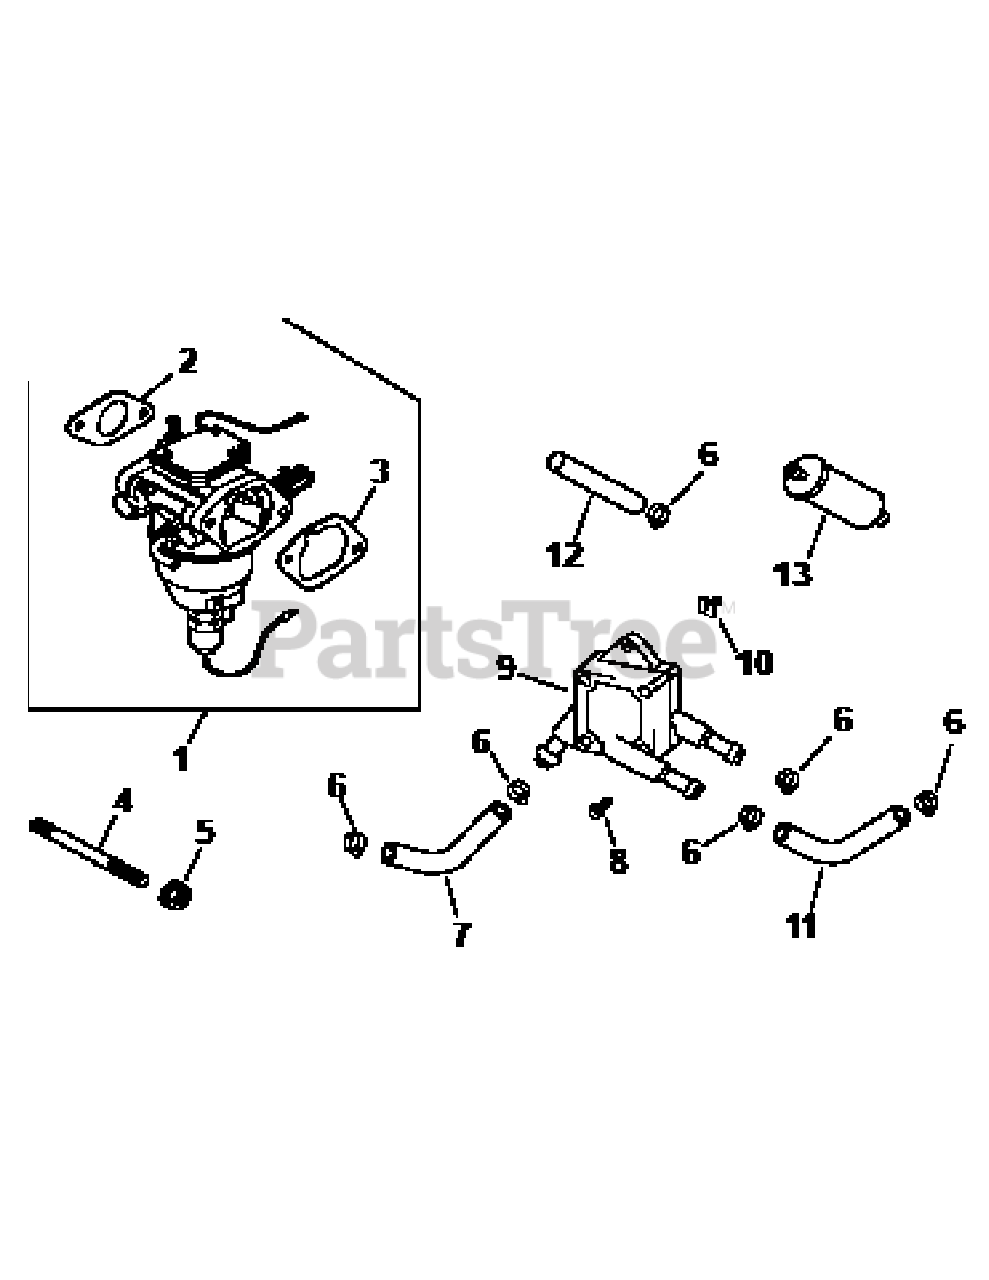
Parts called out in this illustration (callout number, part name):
1	Carburetor w/Gaskets
2	Carburetor Gasket
3	Air Cleaner Base Gasket
6	Hose Clamp
7	Flexible Fuel Line
10	Plastic Nut
11	Fuel Line
12	Fuel Line
13	Fuel Filter
